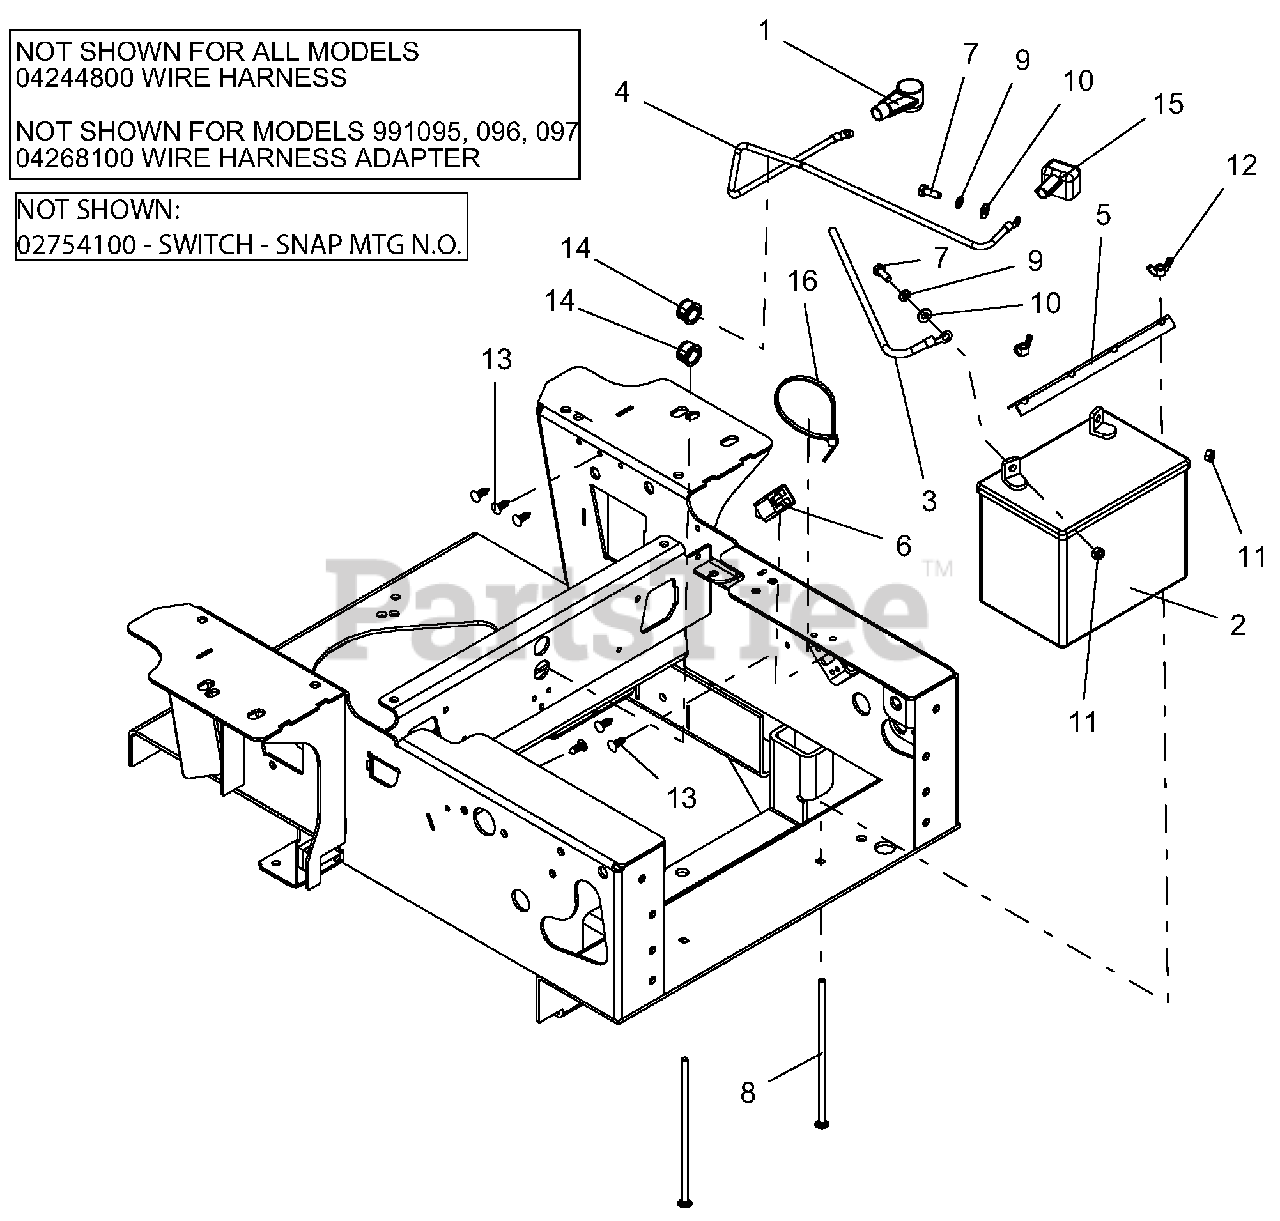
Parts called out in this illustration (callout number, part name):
1	BOOT, BATTERY TERMINAL-RED
2	BATTERY,
3	CABLE, GROUND 22.00"
4	CABLE, STARTER .31 X 23.00 X .31
5	HOLD DOWN - BLK
6	SWITCH, SNAP IN -N.O./N.O
7	BLT-HEX .25-20X.75 GR5 YWZC
8	BLT-RDHDSQNK .25-20X7.50 G2 YWZC
9	WSHR-LK .25X.062 REG YWZC
10	WSHR-FL-STL.281X.62X.065 YWZC
11	NUT-HEX .25-20 YWZC
12	NUT-LOCKING WING 1/4-20
13	RIVET, .25 NYLON PANEL
14	BUSH, PANEL SNAP .687X.875X.56
15	INSULATOR
16	CABLE, TIE 5.50 LG
